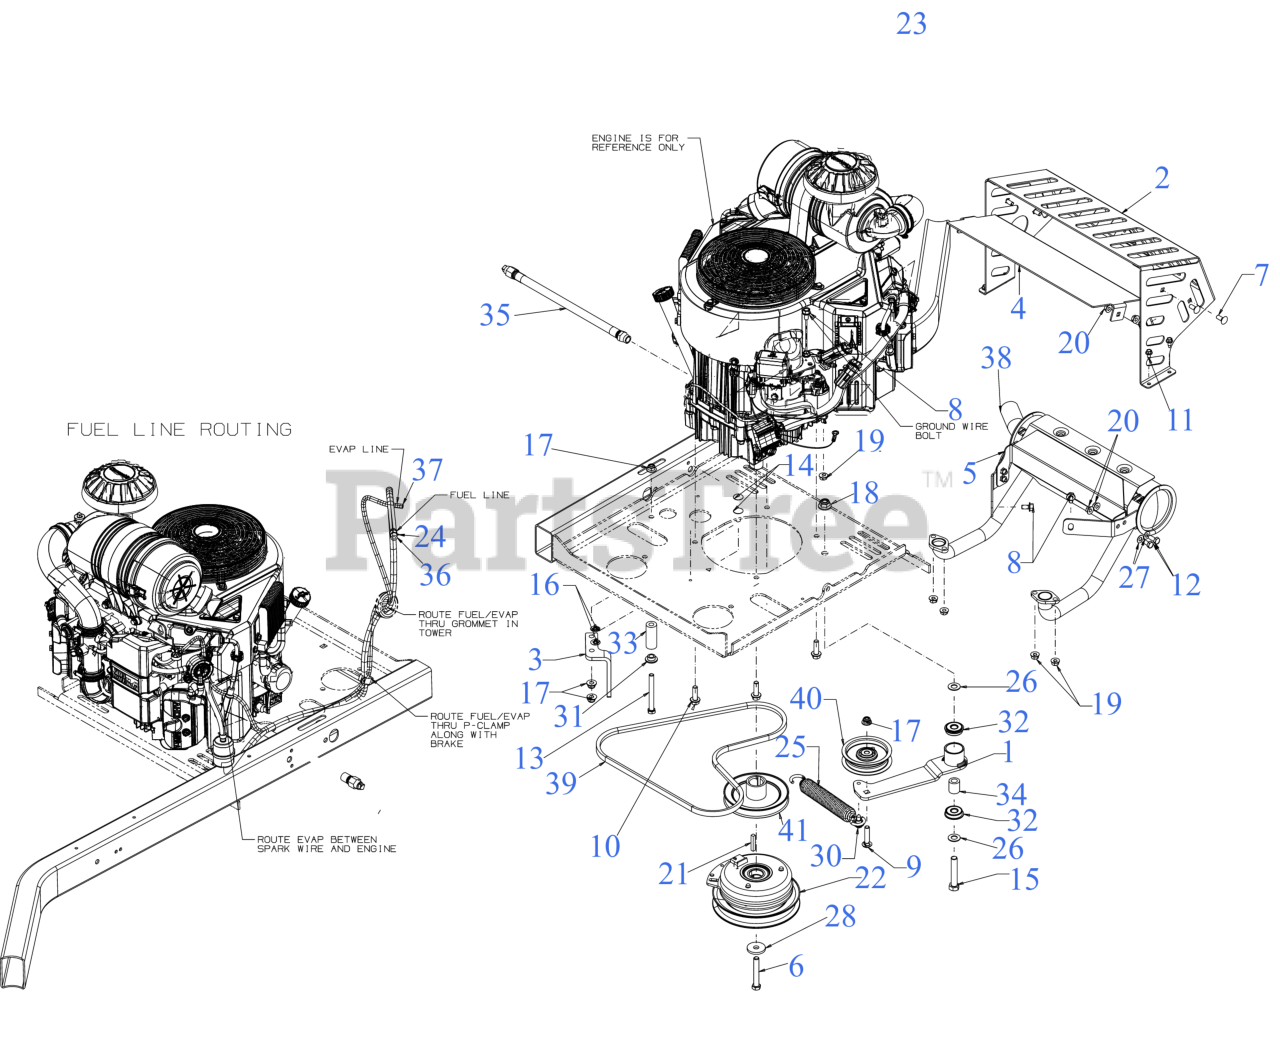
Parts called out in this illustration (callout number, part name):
1	IDLER BRACKET ASSEMBLY
2	MUFFLER SHIELD
3	CLUTCH BRACKET
4	MUFFLER SHEILD BRACKET (INNER)
5	MUFFLER SHIELD
6	SCREW 7/16-20:2.75 GR5
7	CARRIAGE BOLT 5/16-18 x .75
8	SCREW M8 x 1.25 x 16MM GR8.8
9	CARRIAGE BOLT 3/8-16 x 1.75 GR5
10	SCREW 3/8-16 x 1.25 GR5
11	SCREW 1/4-20X.625
12	SCREW 5/16-18 x .75 GR5
13	SCREW 3/8-16 x 3.50 GR5
14	CARRIAGE BOLT 3/8-16 x 1.00 GR5
15	SCREW 1/2-13 x 2.75 GR5
19	HEX FLANGE NUT
20	HEX FLANGE NUT
21	SQUARE KEY 1/4 x 1.50
22	ELECTRIC PTO CLUTCH
23	7" CABLE TIE
24	HOSE CLAMP 1/20
25	SPRING 1.25" DIA x 8.5" LONG
26	FLAT WASHER .510 x .995
27	FLAT WASHER
28	FLAT WASHER .45 x 1.5 x .172 HT
30	SHOULDER SCREW .43X.29X5/16-18 TT
31	SHOULDER SPACER
32	ROLLER BEARING .5X1.37X.44
33	SPACER .41 x .875 x 2.19
34	SPACER 0.51 x 0.88 x 1.00
35	OIL DRAIN HOSE
36	FUEL HOSE LOW PERMEATION 45"
37	VENT HOSE 3/16 ID 51"LG
38	MFLR:FX850:STAND ON
39	BELT SEC A x 51.18
40	FLAT IDLER PULLEY 3.5
41	DRIVE PUMP PULLEY
